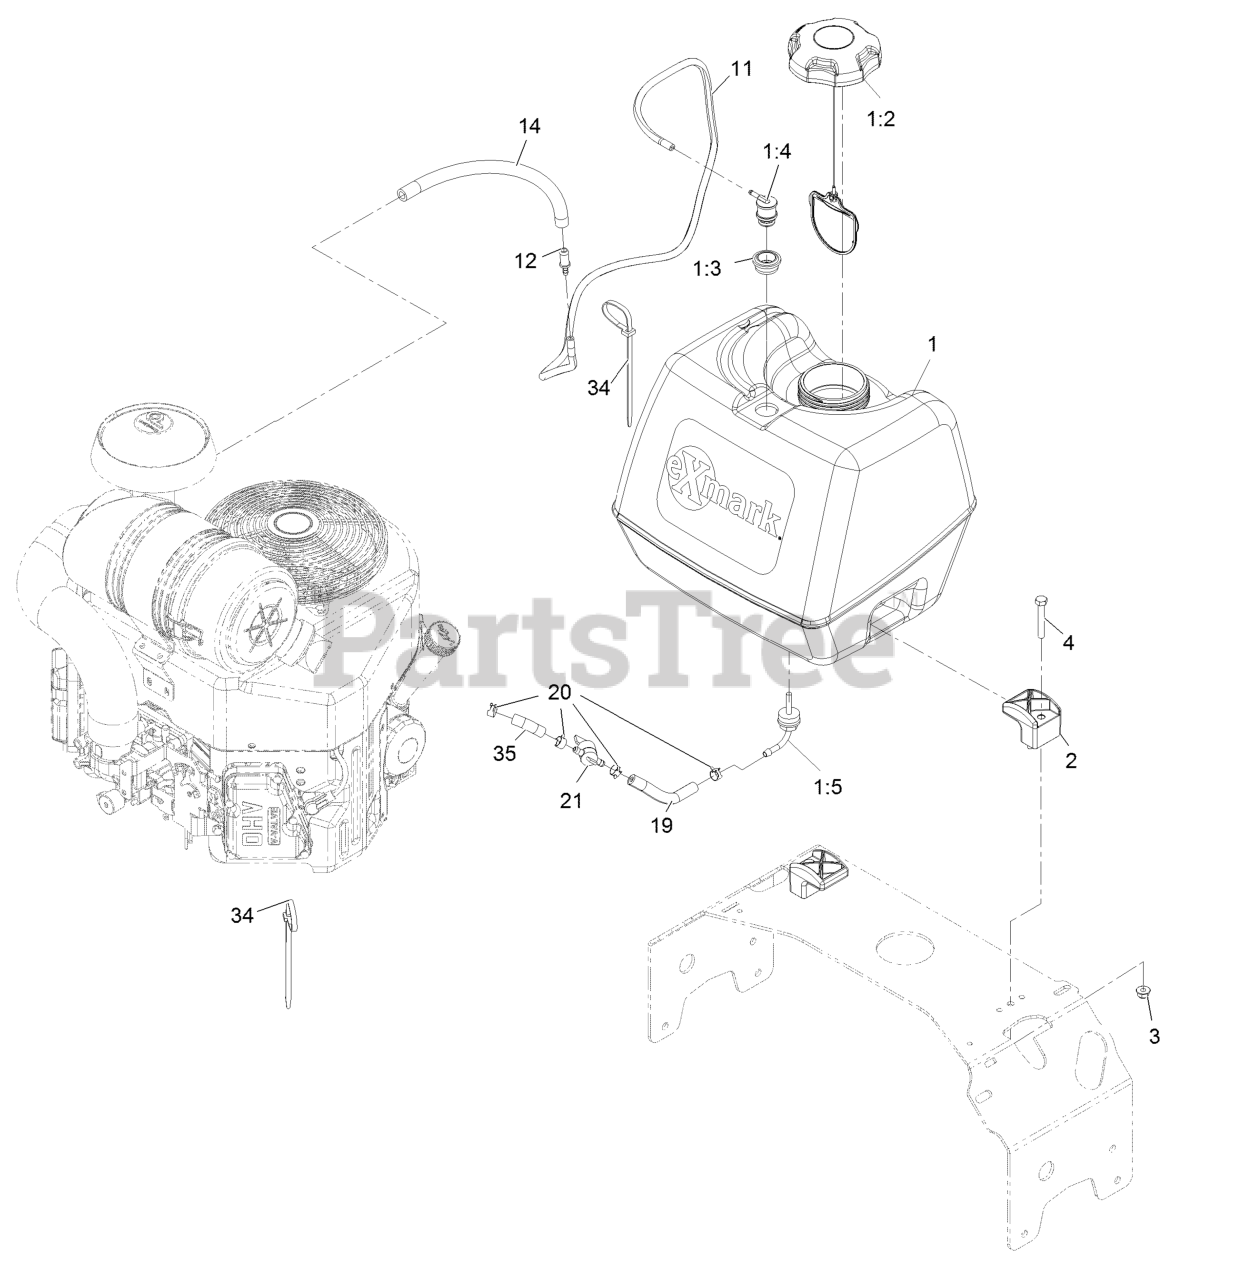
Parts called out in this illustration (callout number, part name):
1	ASM, FUEL TANK
1:3	GROMMET
1:4	VALVE-VENT, FUEL
1:5	FITTING-FUEL, BULKHEAD
3	NUT-HF, NI
4	SCREW-HH
11	HOSE, EMISSIONS
12	FITTING-STRAIGHT
14	HOSE-FUEL
19	HOSE-FUEL
20	CLAMP-HOSE
21	VALVE-FUEL
34	TIE-PLASTIC
35	HOSE-FUEL
